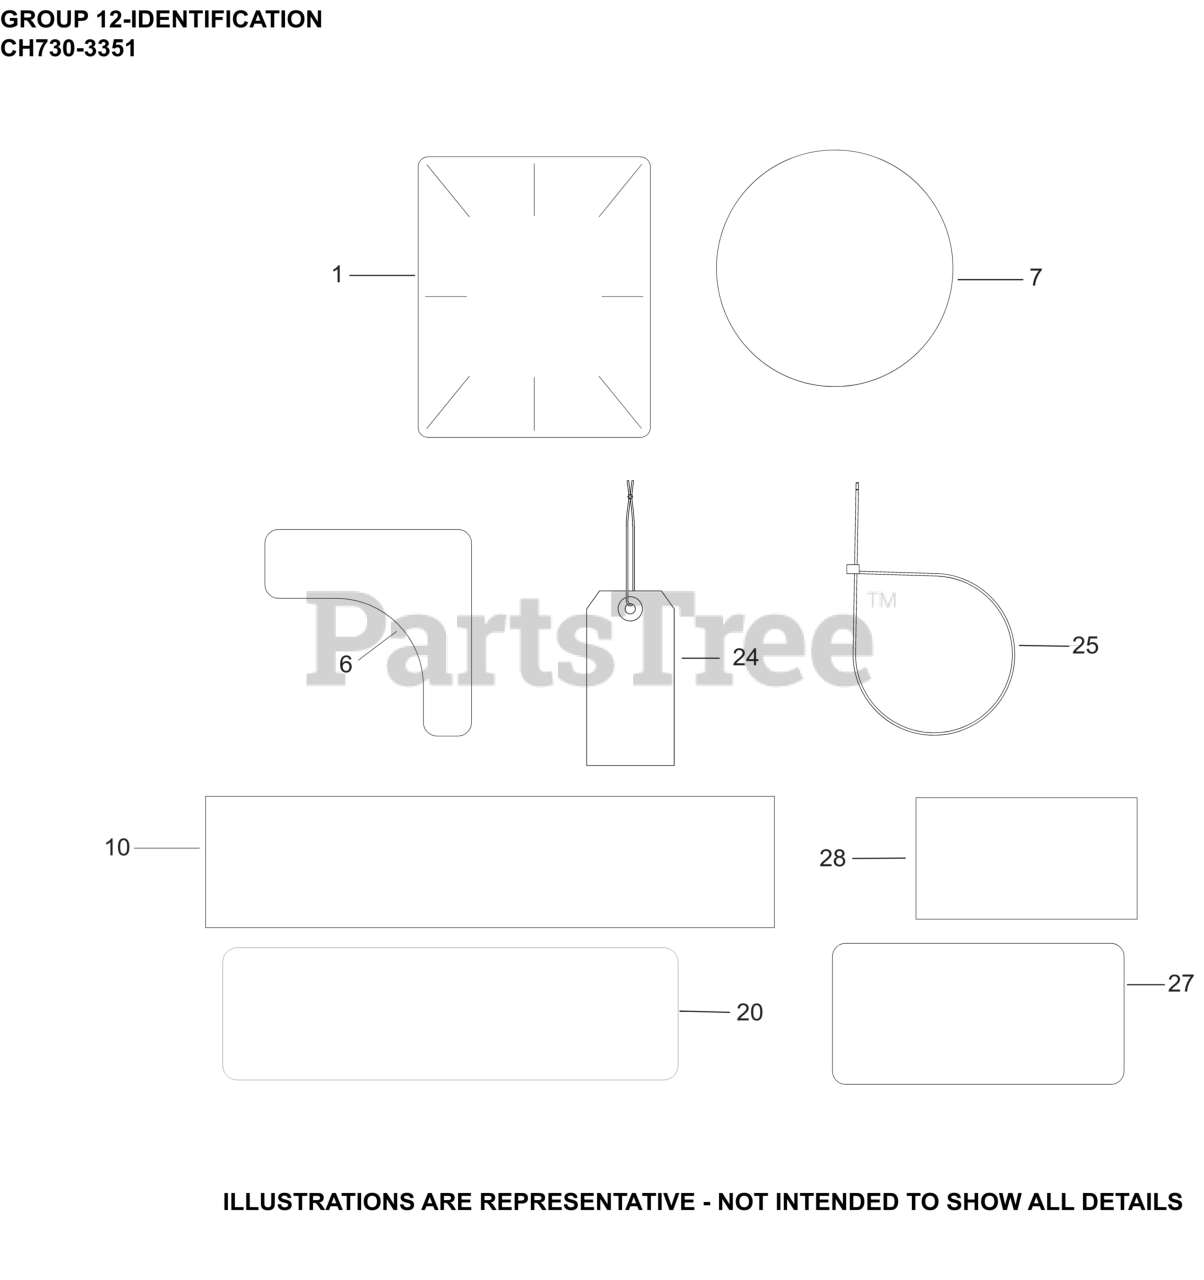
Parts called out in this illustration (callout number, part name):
1	LABEL, CLEAR LAMINATION
6	DECAL, KEY SWITCH
7	LABEL, GRASS SCREEN
10	DECAL, STOPPING INSTRUCTION
20	DECAL LPAC, 23.5 HP/725cc/CH730
24	TAG, HANG (OIL SENTRY)
27	LABEL, CANADIAN COMPLIANCE
28	DECAL, USA
